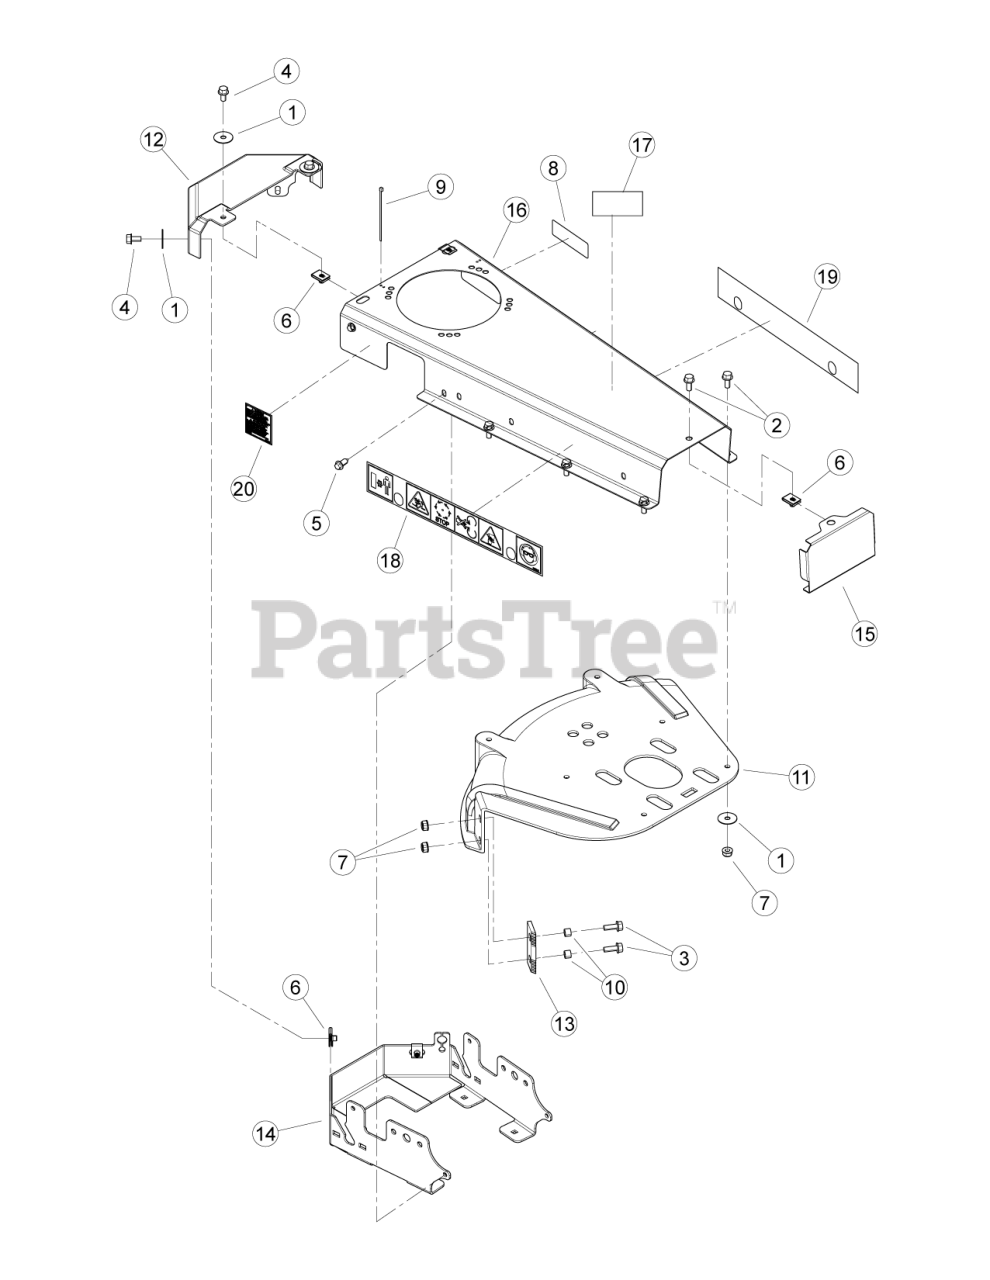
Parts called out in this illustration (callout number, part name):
1	WASHER, 5/16" FENDER ZP
2	BOLT, 5/16 × 3/4 FLANGE NC
3	BOLT, 5/16 × 7/8 FLANGE NC
4	BOLT, 5/16 × 5/8 FLANGE NC
5	SCREW, 11/32-12 × 7/8 FLANGE T-AB
6	NUT 5/16"-18 TINNERMAN U-TYPE
7	NUT, 5/16-18 NYLOCK FLANGE
8	DECAL, SERIAL NUMBER
9	STRAP, 4 IN BLACK
10	SPACER, PLASTIC TRIMMER SHIELD
11	SHIELD, TRIMMER
12	COVER, WT TRANSMISSION
13	KNIFE, RECTANGULAR SHREDDING
14	BRACKET, WT TRANS MOUNT
15	COVER, METAL HW TRIMMERS
16	ASSEMBLY, WT BODY WITH DECALS
17	DECAL, MODEL ECHO WT-1610HSP
18	DECAL, HW SAFETY INFORMATION
19	DECAL, HW MAINTENANCE INFORMATION
20	DECAL, SPARK ARRESTOR
